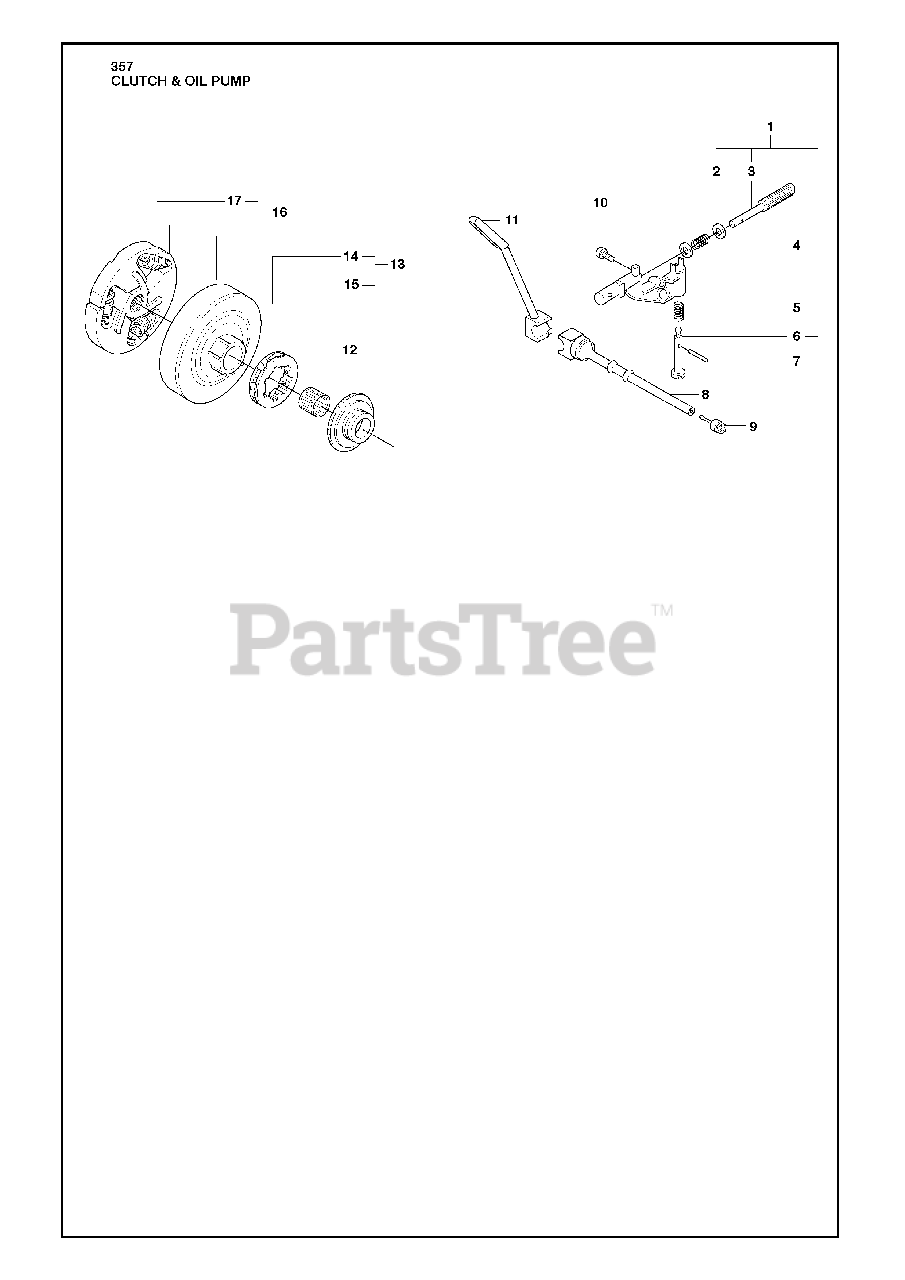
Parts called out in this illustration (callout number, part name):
1	OIL PUMP ASSY
3	PUMP PISTON
8	RP HOSE
9	OIL PLUMMET
12	PUMP GEAR
13	CLUTCH DRUM
14	RIM SPROCKET 7T .325
14	68210 RIMSPROCKET
15	NEEDLE BEARING
16	CLUTCH
